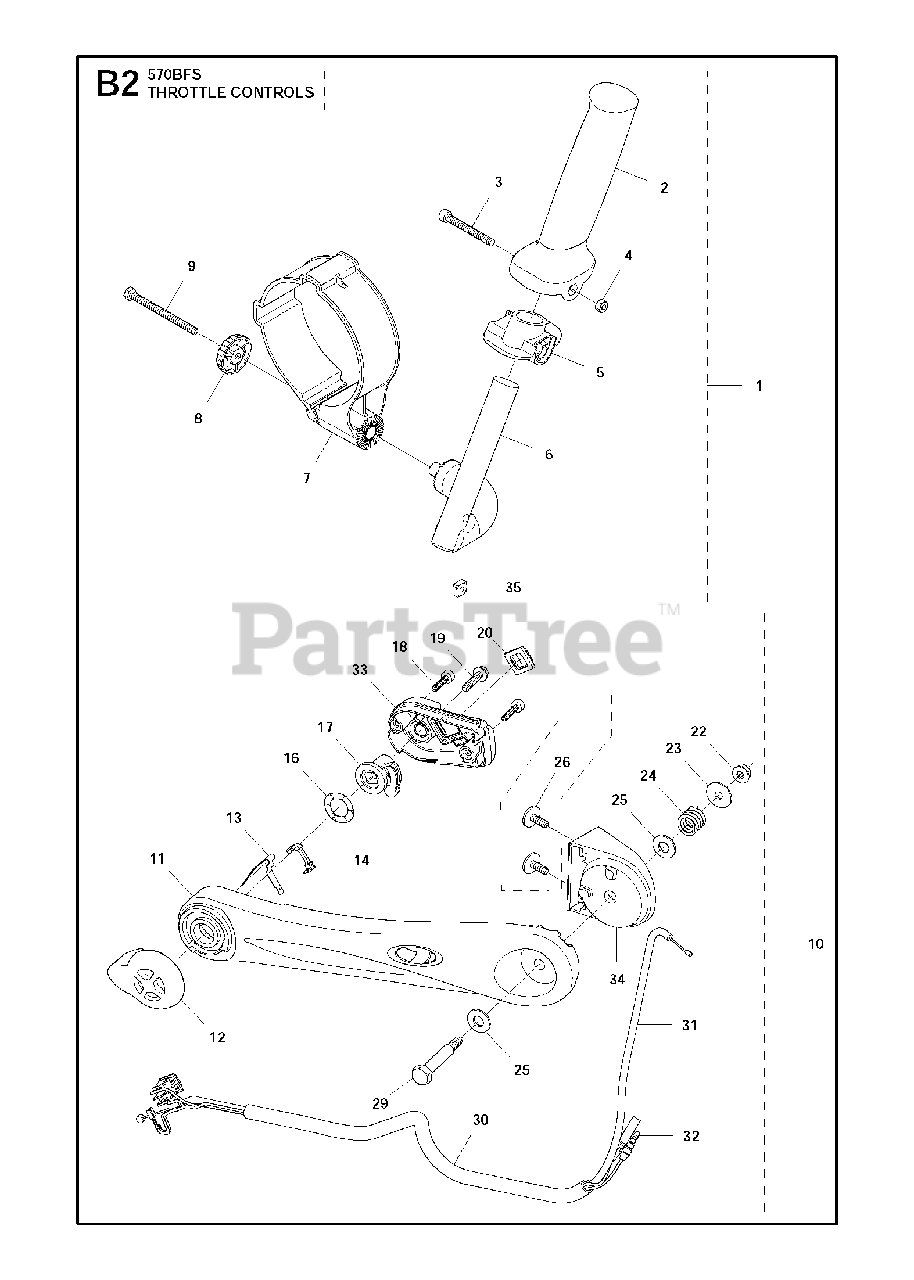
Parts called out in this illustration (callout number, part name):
1	GRIP ASSY BLACK
2	HANDLE
3	SCREW
4	NUT
5	BRACKET
6	BRACKET
7	HANDLE HOLDER
8	KNOB
9	SCREW
11	ARM
12	LEVER,THROTTLE
13	PLATE, CONTACT
14	STOPPER
16	WASHER WAVE
17	PLATE
18	SCREW
19	BOLT
20	CAP SWITCH
22	NUT 8488646000
23	WASHER Z349525440
24	SPRING
25	WASHER
29	BOLT
30	TUBE
31	CABLE
32	SWITCH
33	COVER
34	BRACKET
35	SQUARE NUT M5
